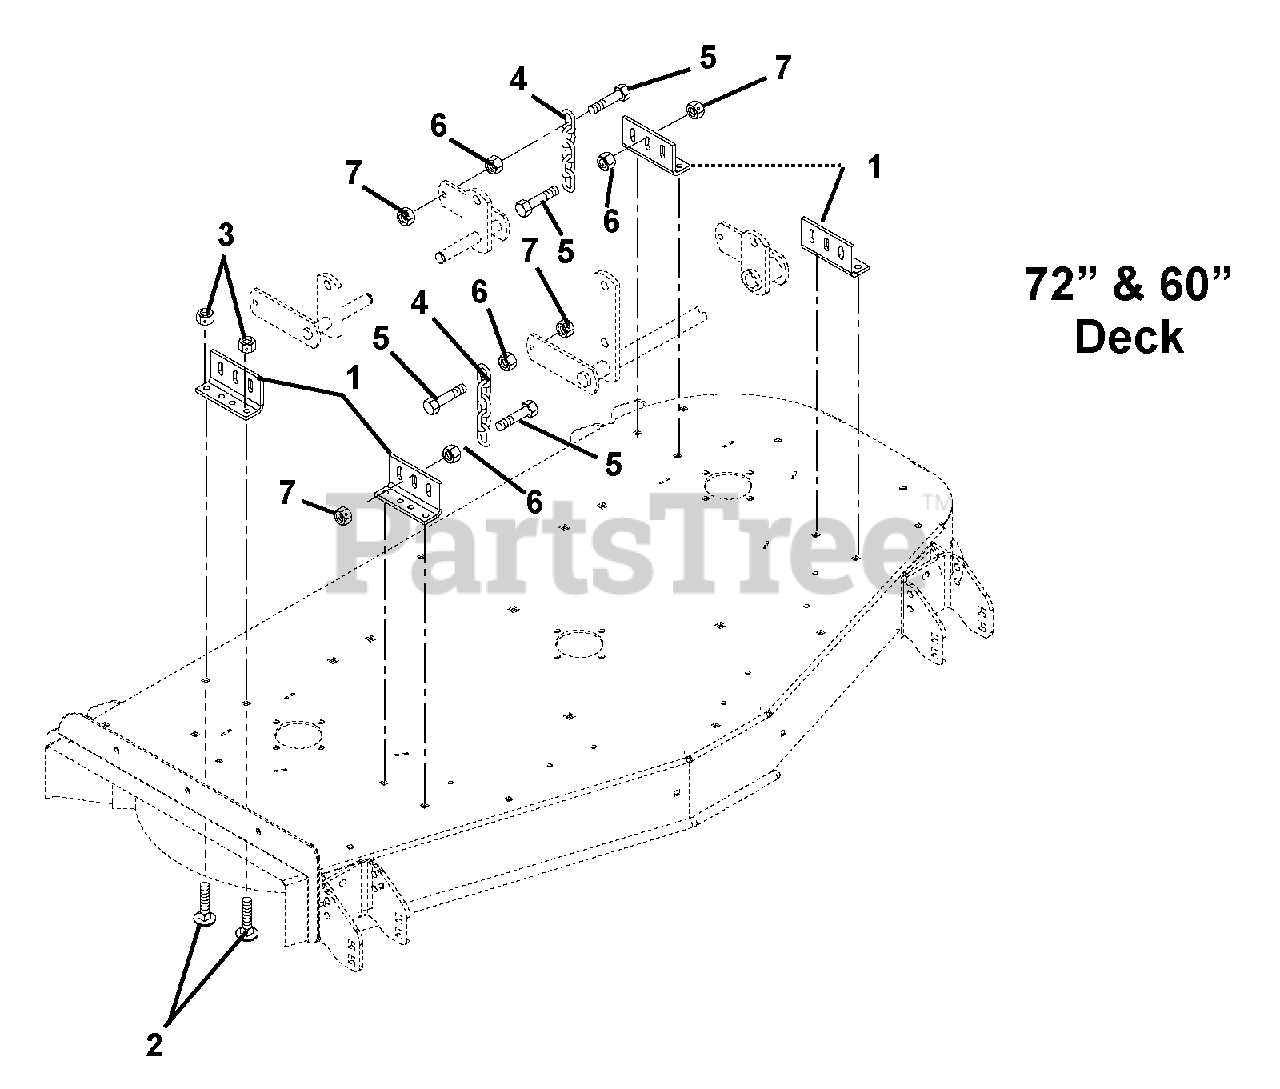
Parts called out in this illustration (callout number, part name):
1	Bracket, Mower Mounting
2	Bolt-Round Head Square Neck .38-16 x 1.00 Grade 2
3	Nut-Locking-Top-Flange .38-16
4	Chain, Link
5	Bolt-Hex M12-1.75 Grade 5
6	Nut, Spin Lock Flange M12-1.75
7	Nut-Locking-Top-Flange M12-1.75
